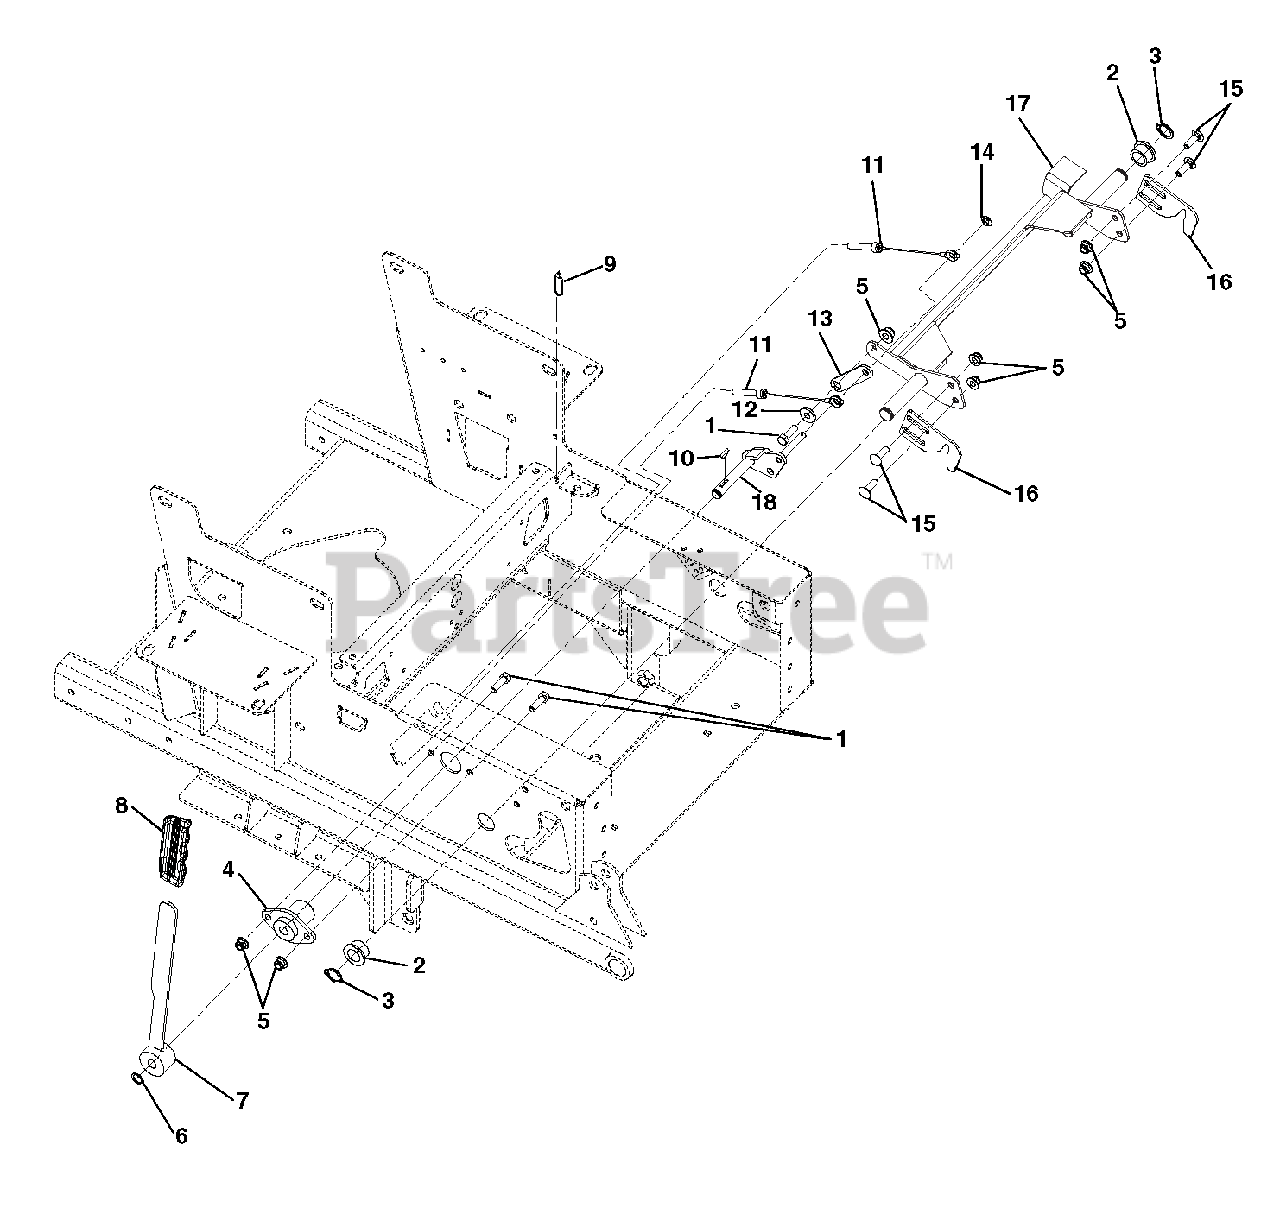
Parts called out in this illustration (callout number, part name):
1	@BLT-HEX .31-18X1.00 GR5 YWZC
2	BSHG-FLG .750X1.000X.625X1.250
3	RG-RTNG-EXT .689X.078
4	BUSHING, FLANGED
5	@NUT-LK-NYL-FLG .31-18 YWZC
6	RG-RTNG-EXT .500X.050 (SNAP)
7	WMT - PARKING BRAKE ARM
8	GRIP, PARKING BRAKE (YELLOW)
9	CABLE TIE LG 5-1/2
10	KEY-WDRF .13X.63 HRD#5
11	CABLE, BRAKE ACTUATING
12	BSHG, FLG .325X.499X.26X.88
13	PLATE, NEUTRAL INTERLOCK
14	NUT-PUSH .312
15	@BLT-RDHDSQNK .31-18X1.00 G5YZ
16	NEUTRAL LOCK LATCH - BLACK
17	WMT, PT100 NEUTRAL LOCK
18	WMT, PARK BRAKE ARM
